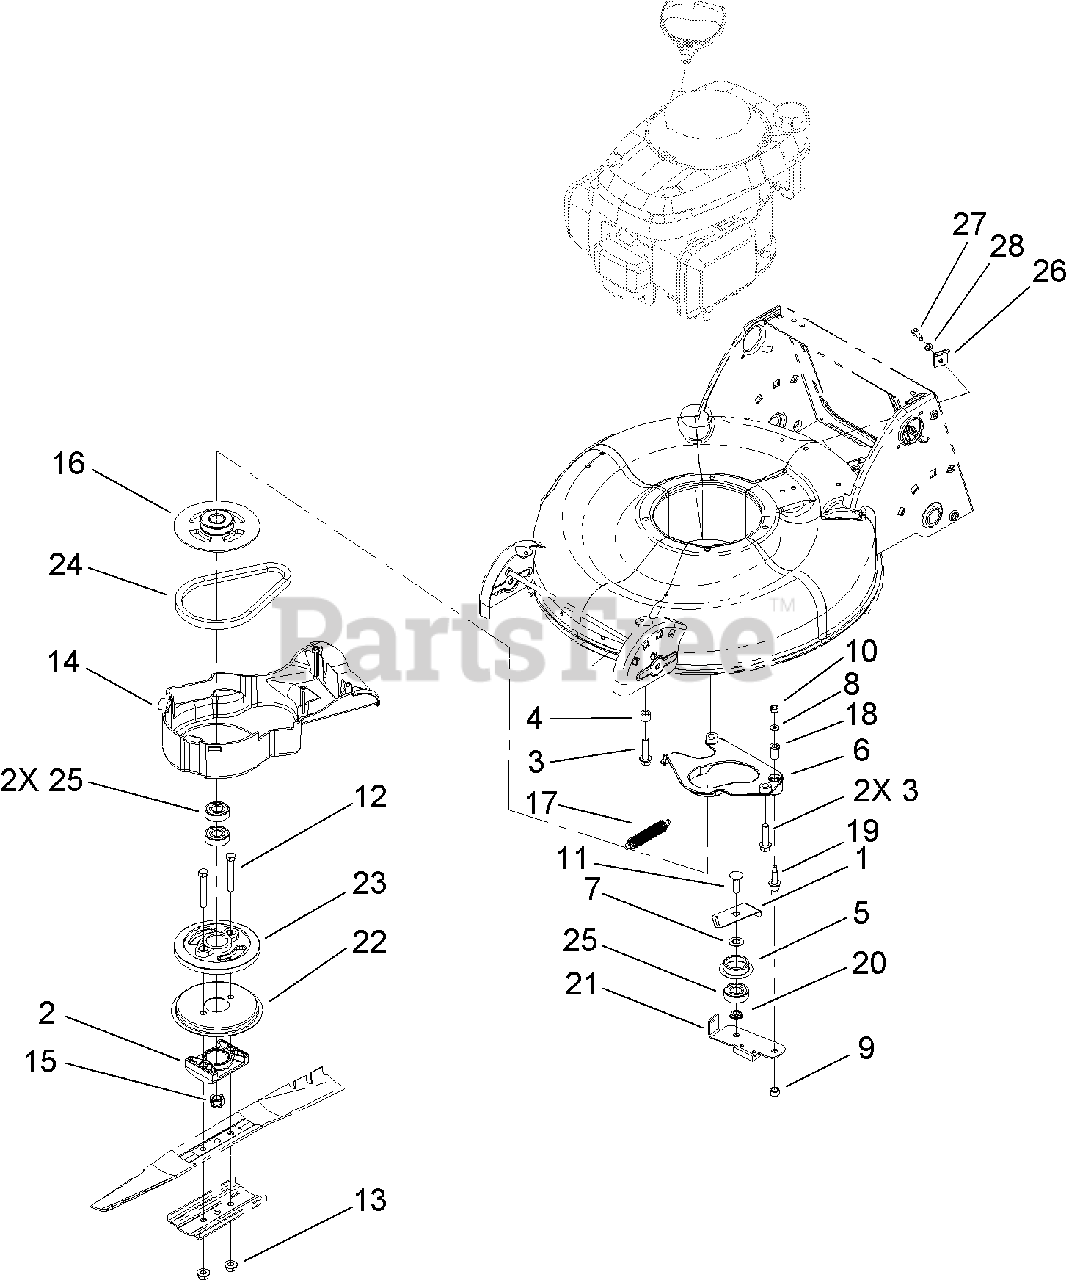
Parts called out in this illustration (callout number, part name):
1	PLATE-GUIDE
2	SUPPORT-BLADE
3	SCREW-HWH
4	TUBE-SPACER
5	RETAINER-BELT
6	PLATE-ANCHOR
8	WASHER-FLAT
10	NUT-LOCK, NI
11	SCREW-CARR
12	SCREW-HH
13	NUT-LOCK
14	COVER
16	PULLEY
17	SPRING-TENSION, BRAKE
19	BOLT-SHOULDER
20	SPACER-BEARING
21	BRAKE ARM ASM
22	DISC
23	DRUM
25	BEARING-BALL
26	CLAMP-CABLE
27	SCREW-HH
28	WASHER-LOCK
